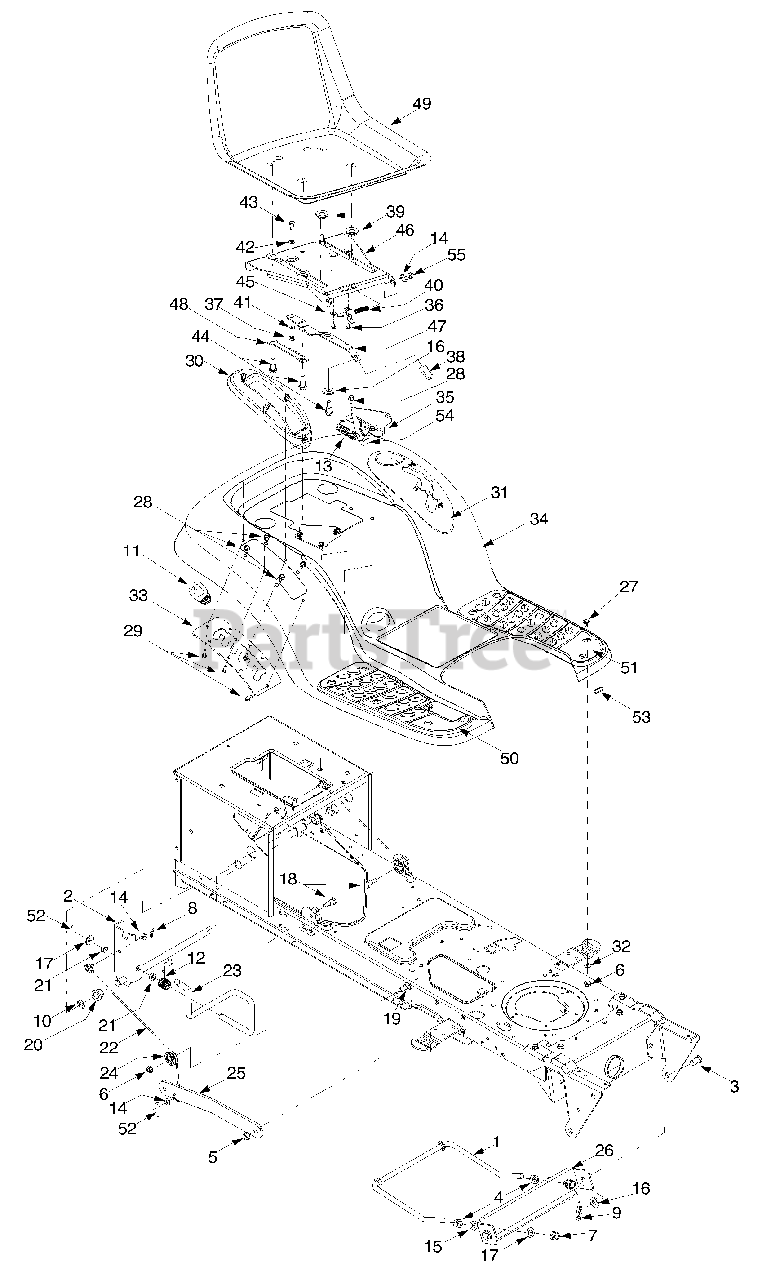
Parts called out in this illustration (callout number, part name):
1	Deck Stabilizer Rod
3	Clevis Pin, .5 x .78
4	Hex Nut, 1/2-13
5	Flange Lock Nut, 3/8-16
6	Flange Lock Nut, 5/16-18
7	Hex Nut, 1/2-13
8	Internal Cotter Pin
9	Internal Cotter Pin
11	Handle Grip
12	Torsion Spring
13	Extension Spring, .872 x 3.4
14	Flat Washer, 5/16
15	Lock Washer, 1/2
16	Flat Washer, .31 x 1.062 x .134
17	Flat Washer, .51 x 1.12 x .06
18	Hex Cap Screw, 5/16-18 x .62
19	Shoulder Screw, 3/8-16
20	Hex Flange Bearing
21	Snap Flange Bearing
22	Lift Cable, 16.16
23	Lift Handle
24	Roller Pulley
27	Carriage Bolt, 5/16 x .62
28	Self-tapping Screw, 5/16-18 x .625
29	Self-tapping Screw, 1/4-15 x .75
30	Lift Lever Cover
31	Shift Lever Cover w/ Cup Holder
32	Flat Washer, .349 x 1.0 x .063
36	Screw, #10-16 x .375
37	Hex Flange Lock Nut, 1/4-20
38	Seat Adjuster Grip
40	Compression Spring, .41 x 1.5
41	Spring Washer, .265 x .562 x .025
42	Flat Washer, .344 x .62 x .03
43	Shoulder Screw, .340 x .285, 1/4-20
44	Shoulder Screw, .50 x .50, 3/8-16
45	Seat Stop
48	Seat Adjustment Selector
49	High Back Seat, Black
50	RH Foot Pad
51	LH Foot Pad
52	Cotter Pin
53	Trim Strip
54	Seat Lift Bracket
55	Speed Nut
